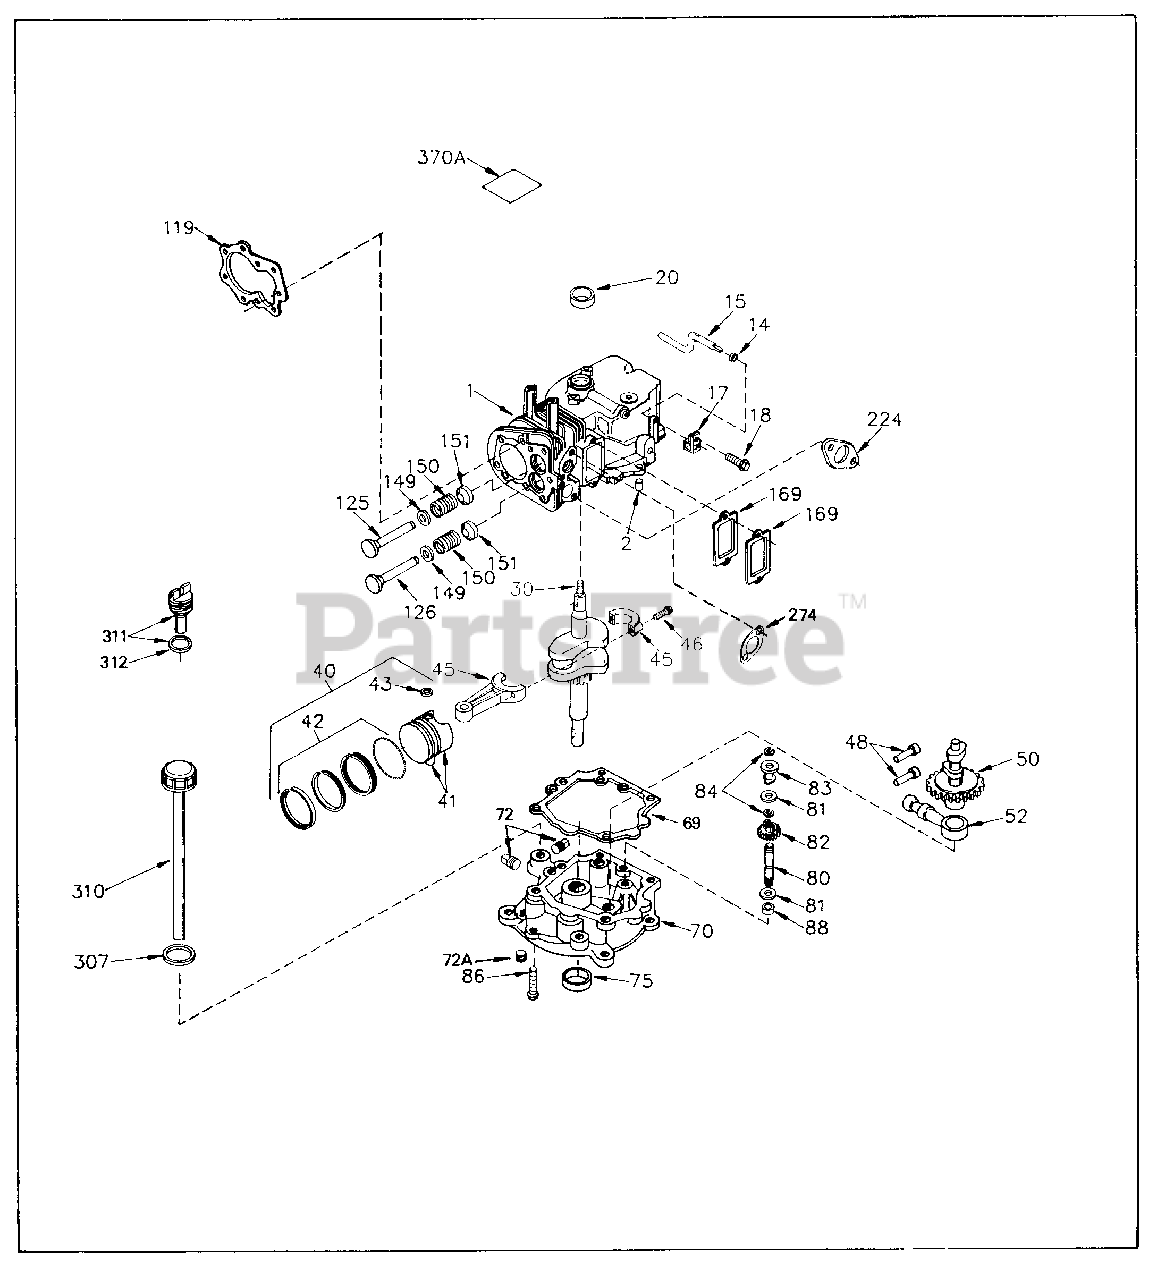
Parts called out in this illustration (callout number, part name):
1	"Cylinder (Incl. 2, 20, 311 & 312) 2-5 /8" Bore
2	Dowel Pin
14	Flat Washer
15	Governor Rod
17	Governor Lever Clamp
18	Screw, 8-32 x 5/16"
20	Oil Seal
30	Crankshaft
40	Piston, Pin & Ring Set (.020" OS)
40	Piston, Pin & Ring Set (Std.) 2-5/8"B ore
40	Piston, Pin & Ring Set (.010" OS)
41	Piston & Pin Ass'y. (Std.)(Incl. 43) 2-5/8"
41	Piston & Pin Ass'y. (.010" OS) Incl. 43
41	Piston & Pin Ass'y. (.020" OS) Incl. 43
42	Ring Set (Std.) (2-5/8" Bore)
42	Ring Set (.010" OS)
42	Ring Set (.020" OS)
43	Piston Pin Retaining Ring
45	Connecting Rod Ass'y. (Incl. 46)
46	Connecting Rod Screw
48	Valve Lifter
50	Camshaft (MCR)
52	Oil Pump Ass'y.
69	Mounting Flange Gasket
70	Mounting Flange Incl. 72,72A,75,80,81 ,311,312
72	Oil Drain Plug (Sq. hd., 1/4-18)
72A	Oil Drain Plug (Sq. hd., 1/4-18)
75	Oil Seal
80	Governor Shaft
81	Flat Washer
82	Governor Gear Ass'y.
83	Governor Spool
84	Retaining Ring
86	Screw, 1/4-20 x 1-1/4"
88	Governor Gear Spacer
119	Cylinder Head Gasket
125	Exhaust Valve (Std.)(Incl. 151)
125	Exhaust Valve (1/32" OS) (Incl. 151)
126	Intake Valve (Std.) (Incl. 149)
126	Intake Valve (1/32" OS) (Incl. 149)
149	Valve Spring Cap
150	Valve Spring
151	Lower Valve Spring Cap
169	Valve Cover Gasket
224	Intake Pipe Gasket
274	Muffler Gasket
307	Oil Fill Plug Gasket
310	Oil Dipstick (Incl. 307)
311	Oil Fill Plug (Incl. 312) also availa ble in Packaged Part #740079
312	Oil Fill Plug Gasket
370A	Lubrication Decal
